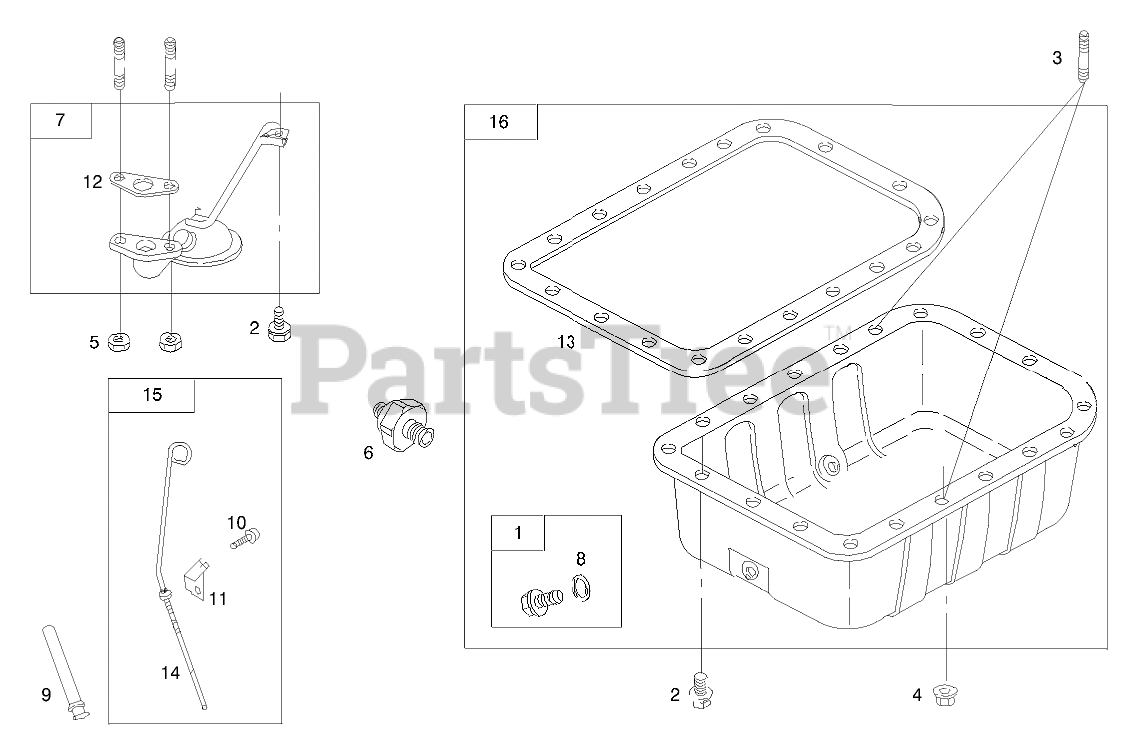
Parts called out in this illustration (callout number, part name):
1	PLUG-DRAIN, OIL
2	SCREW-HEX
3	STUD-METRIC
4	NUT-HEX, METRIC
4	NIPPLE ASM
5	NUT-HEX, METRIC
5	VALVE ASM
6	SWITCH-PRESSURE, OIL
7	SCREEN-PUMP, OIL
8	WASHER-SEAL
9	TUBE-DIPSTICK
9	GASKET-SET
10	SCREW-HEX
11	Bracket-Support
12	GASKET-STRAINER, OIL
13	GASKET-PAN, OIL
14	DIPSTICK
14	VALVE OVERHAUL KIT
15	DIPSTICK
15	SHAFT-GEAR
16	PAN-OIL
